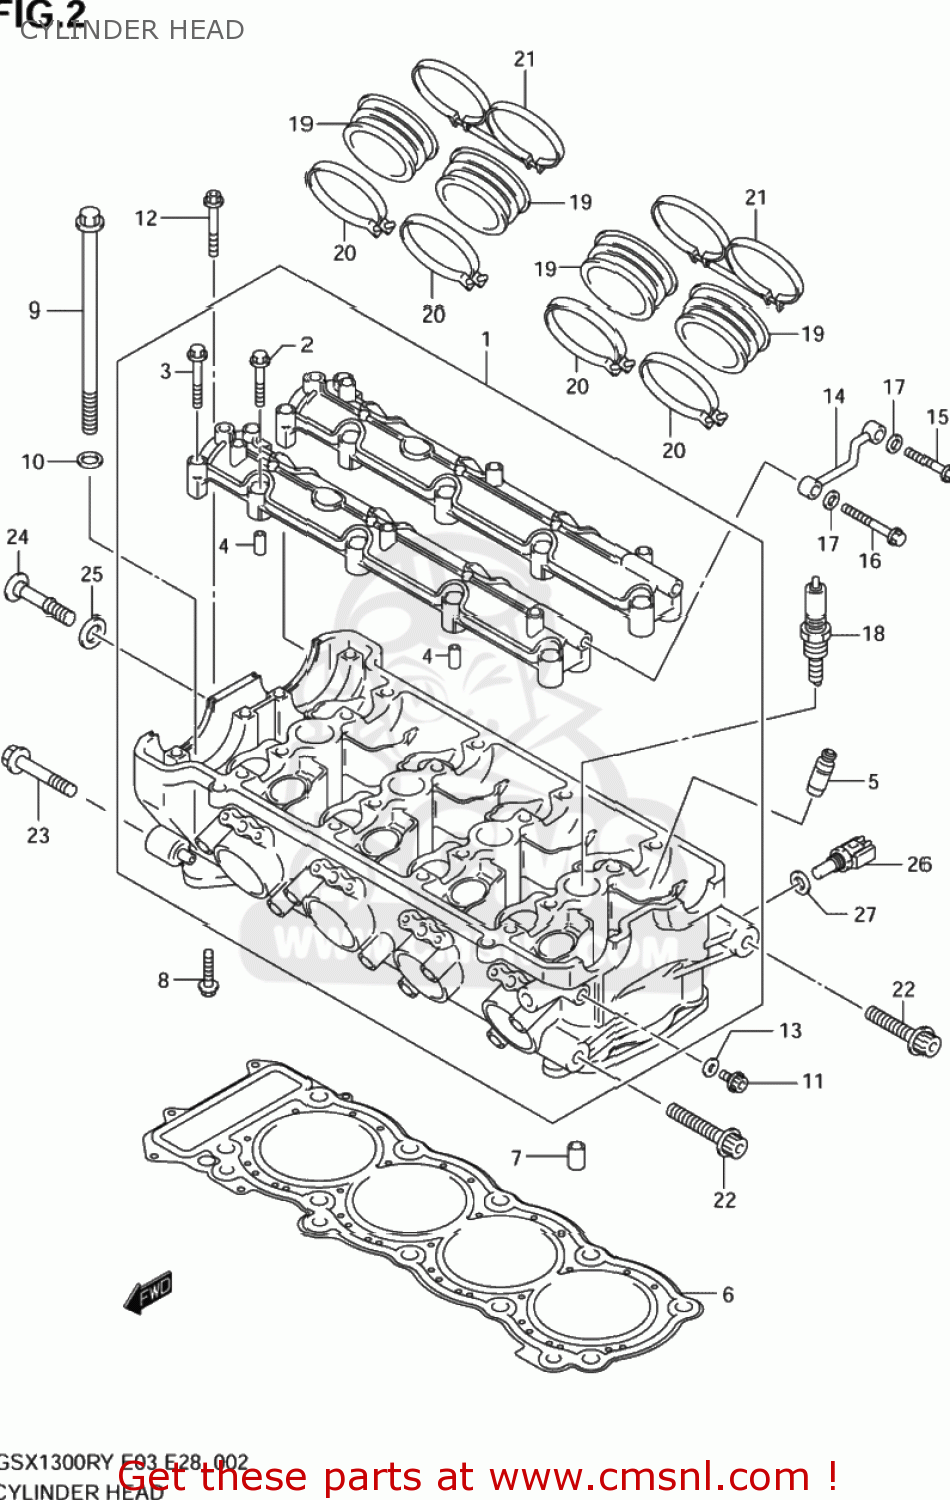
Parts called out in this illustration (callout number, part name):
1	HEAD ASSY,CYLINDER
2	BOLT(6X39)
3	BOLT(6X45)
4	PIN(6.2X8X16)
5	GUIDE,VALVE
6	GASKET,CYLINDER HEAD (NAS)
7	PIN
8	BOLT
9	BOLT(10X175)
10	WASHER(10.5X19X2)
11	BOLT
12	BOLT,CYL.OIL P
13	GASKET(5.8X13X1.2) (NAS)
14	PIPE,CYLINDER HEAD OIL
15	BOLT
16	BOLT (6X45)
17	WASHER
18	PLUG,SPARK(CR8E)
19	PIPE,INTAKE
20	CLAMP
21	CLAMP,INTAKE P
22	BOLT
23	BOLT
24	BOLT,CYL HEAD SIDE FACE
25	WASHER,HEAD COVER
26	SENSOR,WATER TEMP
27	GASKET(12X17X1) (NAS)
